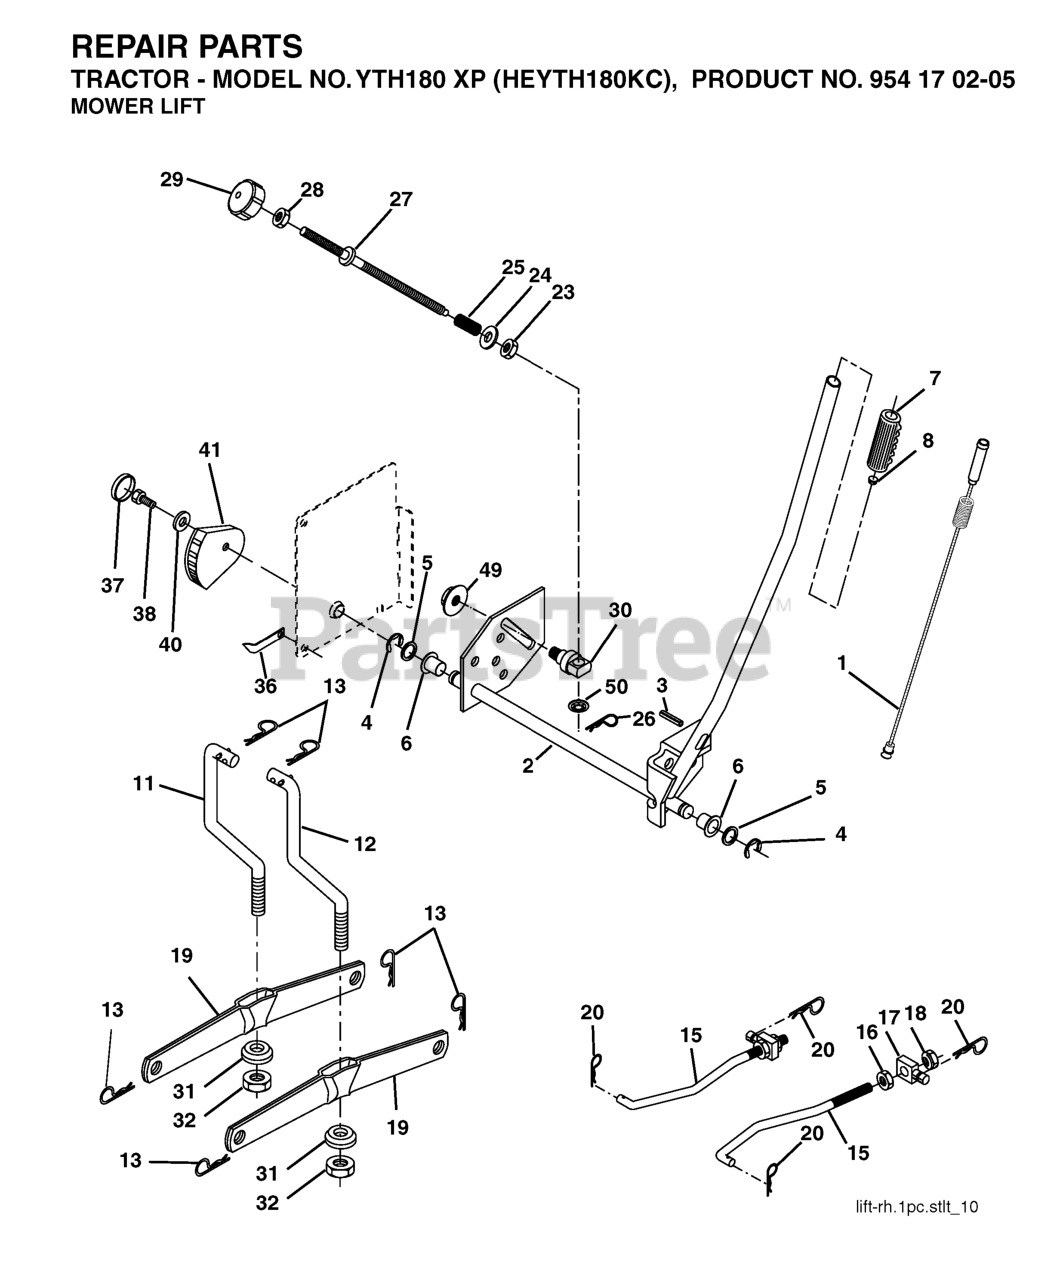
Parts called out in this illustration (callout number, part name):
1	WIRE ASM INNER W/ PLUNGER LT
2	SHAFT ASM R HANDLE
3	PIN GROOVE.
4	RETAINING RING LT
6	BEARING.NYLON
7	GRIP HANDLE
8	PLUNGER BUT KIT
11	LINK LIFT LH
12	LINK LIFT RH
13	RETAINER-SPRNG RB
15	LINK.SUSPENSION.FRONT
16	NUT.HEX.JAM.1/2-13
18	NUT.LK.W/WSH.1/2.
19	ARM.REAR.SUSPENSION
20	SPRING RETAINER
25	SPRING**
26	RETAINER CLIP
27	ROD ADJ LIFT
28	NUT
29	KNOB INF 3/8-16
31	BEARING.PIVOT.LIFT
32	NUT CROWNLOCK 3/8-24
36	POINTER, HEIGHT INDICATOR(2 2)
38	SCREW 5/16-18X1
41	IND. HEIGHT STLT
49	NUT
50	NUT PUSH M
